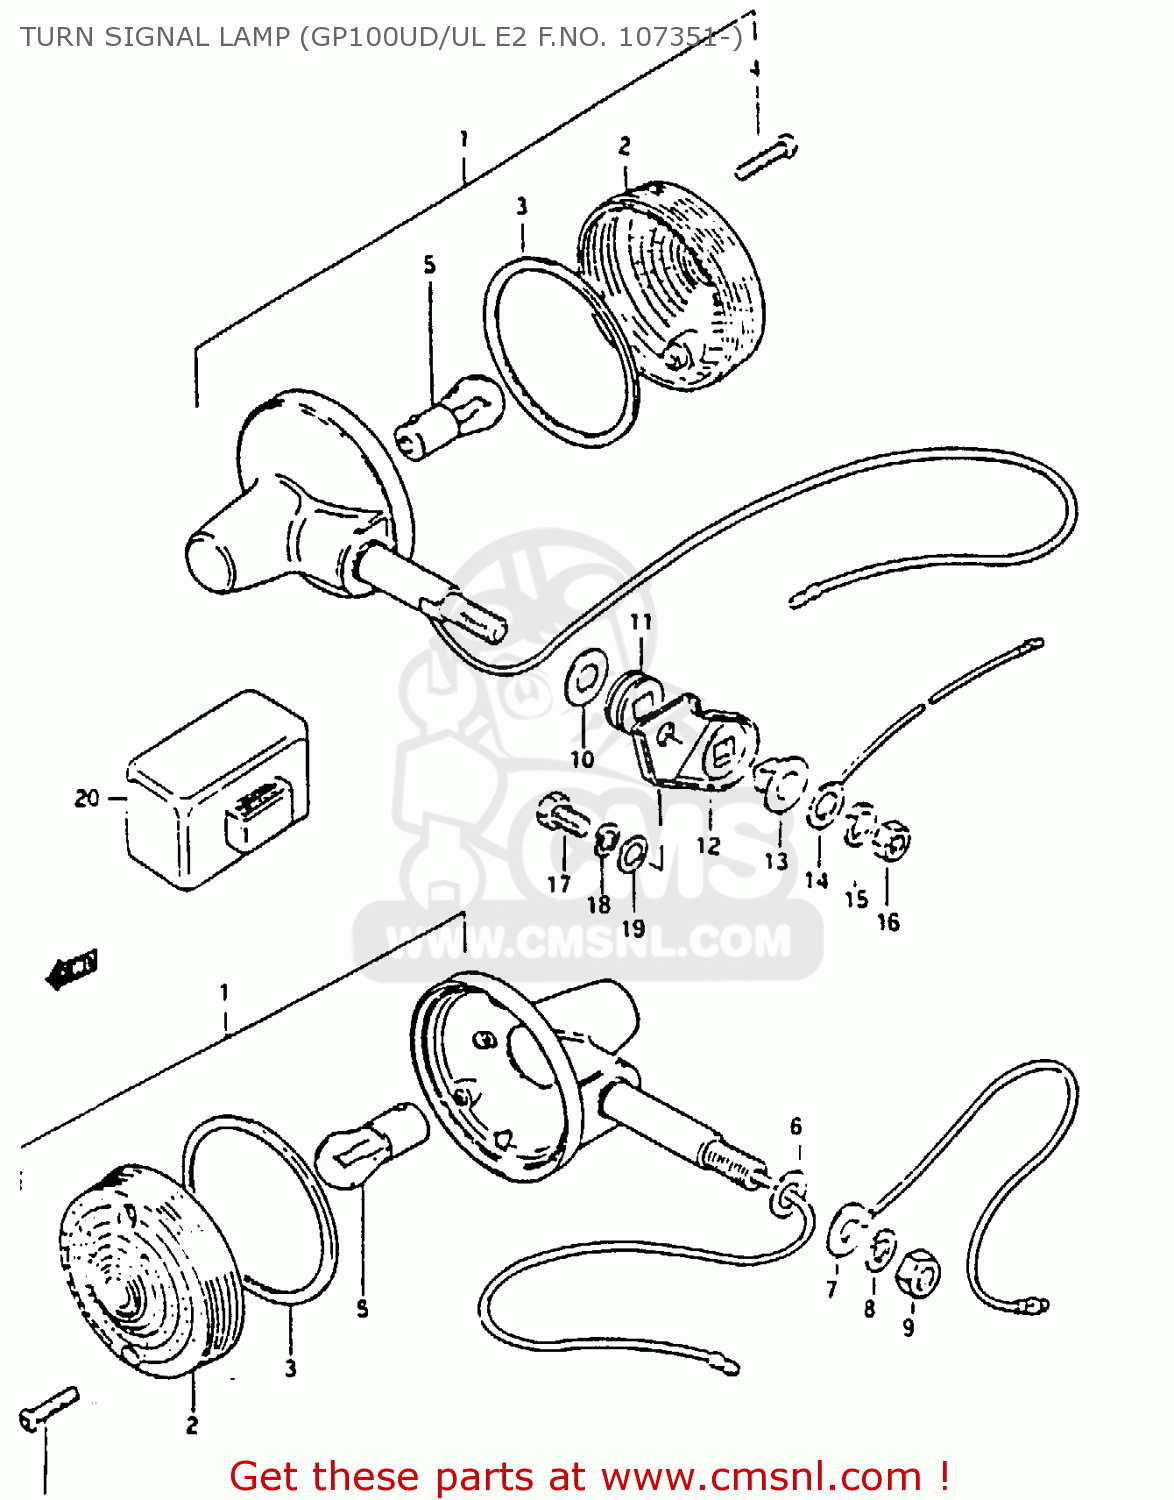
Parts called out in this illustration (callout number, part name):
1	LAMP, REAR TURN SIGNAL
2	LENS
3	GASKET (NAS)
4	GASKET (NAS)
5	BULB (6V,21W)
6	WASHER
7	LEAD WIRE,EARTH
8	WASHER,LOCK,10
9	NUT
10	WASHER (10.5X30X2.3)
11	CUSHION
12	BRACKET, REAR RH
13	SPACER
14	LEAD WIRE,EARTH
15	WASHER,LOCK,10
16	NUT
17	BOLT,8X16
18	LOCK WASHER
19	WASHER
20	RELAY ASSY, TURN SIGNAL
